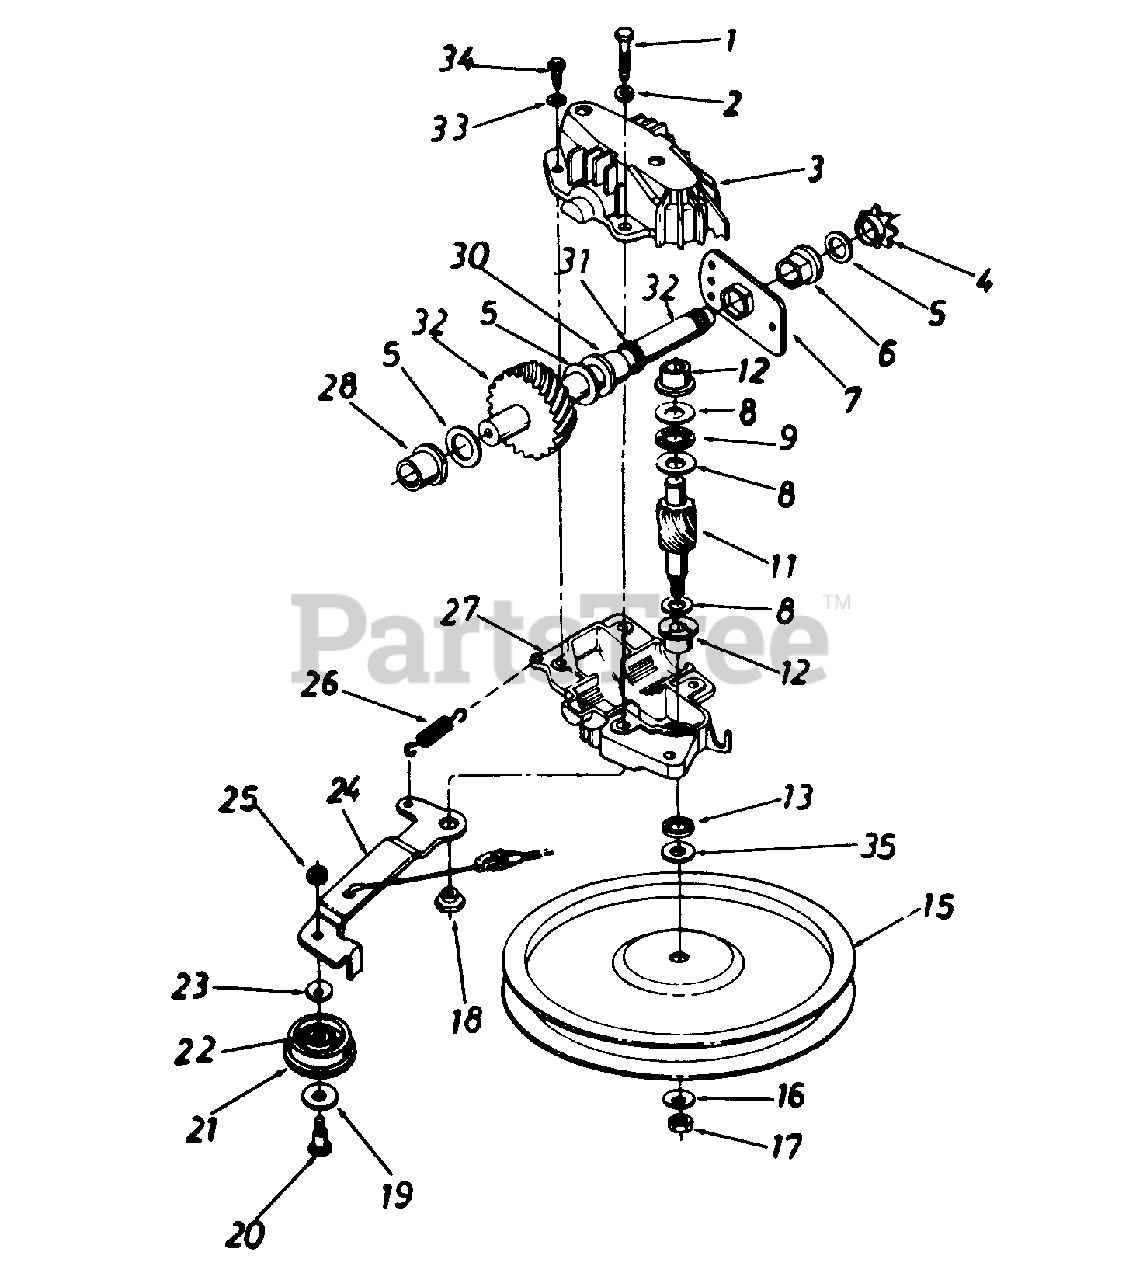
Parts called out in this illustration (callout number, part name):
1	Hex Bolt 1/4-20 x 1.25" Lg. w/Patch
2	L-Wash. 1/4" I.D.
3	Upper Hsg. Half
4	#48 Sprocket 7 Tooth x 1/2 Pitch
5	Fl-Wash. 5/8" I.D. x .030
6	Hex Flange Brg. .631" I.D.
8	Thrust Wash. .382" I.D. x .70" 0.D.
9	Thrust Bearing .375" I.D. x .812" 0.D.
11	11 Tooth Pinion Shaft
12	Flange Bearing
15	Fl-Pulley 5.06" O.D.
16	Bell-Wash. .265" I.D. x 75"
17	Hex L-Nut 1/4-28 L.H. Thd.
18	Shld. Spacer.375" Dia. x .170
19	Fl-Wash. .390" I.D. x 1.0"
20	Shld. Bolt .375" Dia. x .40"
21	Fl-Idler Plastic 1.50" Dia.
22	Needle Brg. .375" x .31
23	Bell-Wash. .265" I.D. x 75"
24	Idler Brk't. Ass'y.
25	Hex Patch L-Nut 1/4-28 Thd.
26	Extension Spring 1.12" Lg.
27	Lower Hsg. Half
28	Flange Bearing .566 Dia.
30	Flange Bearing .629 Dia.
31	Oil Seal .625 Dia.
32	Gear Shaft Ass'y.
33	L-Wash. #10 I.D.
34	Hex Tap Scr. #10 x .62"
35	Hex Washer .26" x .88"
